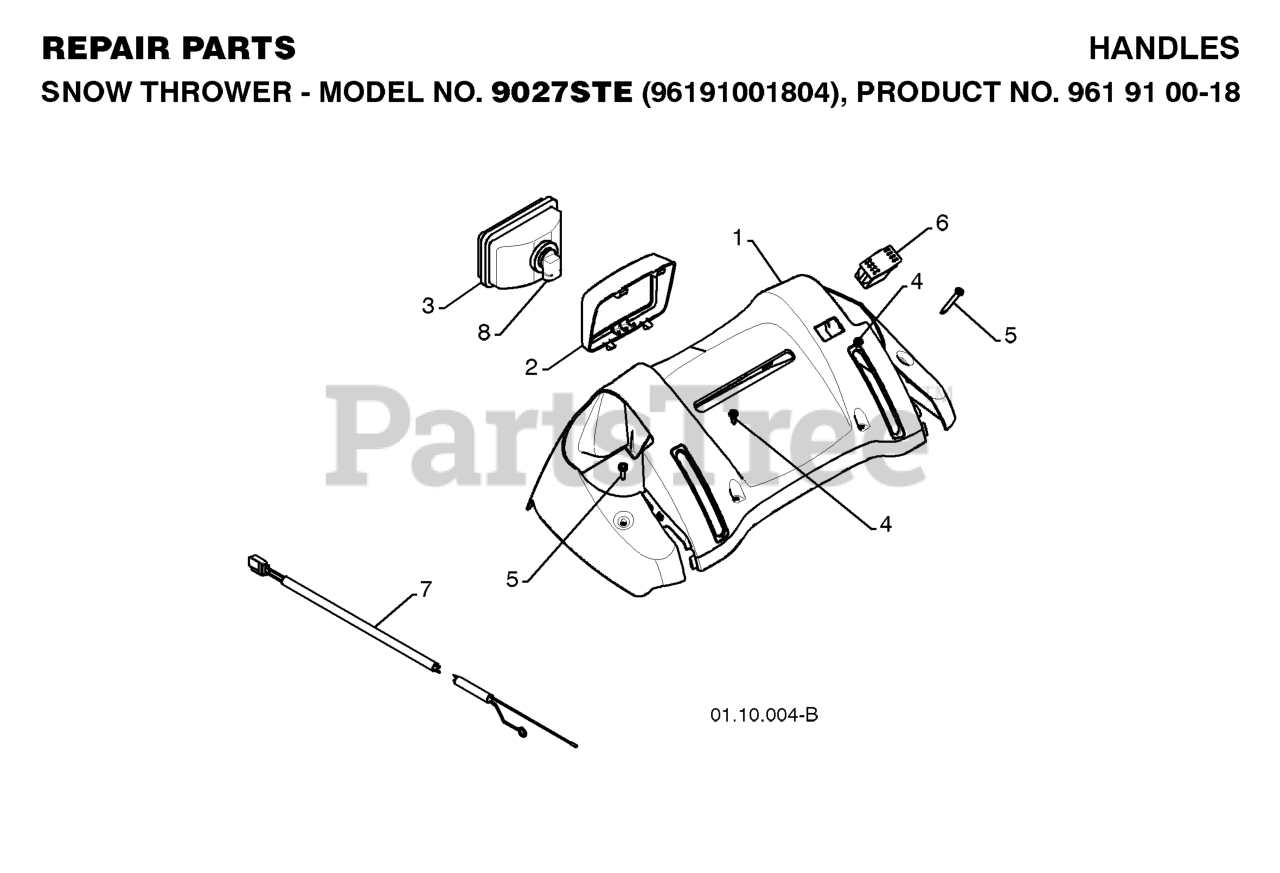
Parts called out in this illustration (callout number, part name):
1	PANEL.CONSOLE.LIGHT.REM.SWITCH
2	BEZEL.HEADLIGHT.BLACK
3	HEADLIGHT.HALOGEN.SNOW
4	SCREW, HEX HEAD, TAPPING
5	SCREW, HEX HD TAPPING #10-24 1
6	SWITCH.HEATED.GRIP
7	HARNESS.WIRE.LIGHT/GRIP.SNOW
8	BULB.HEADLIGHT.HALOGEN.
